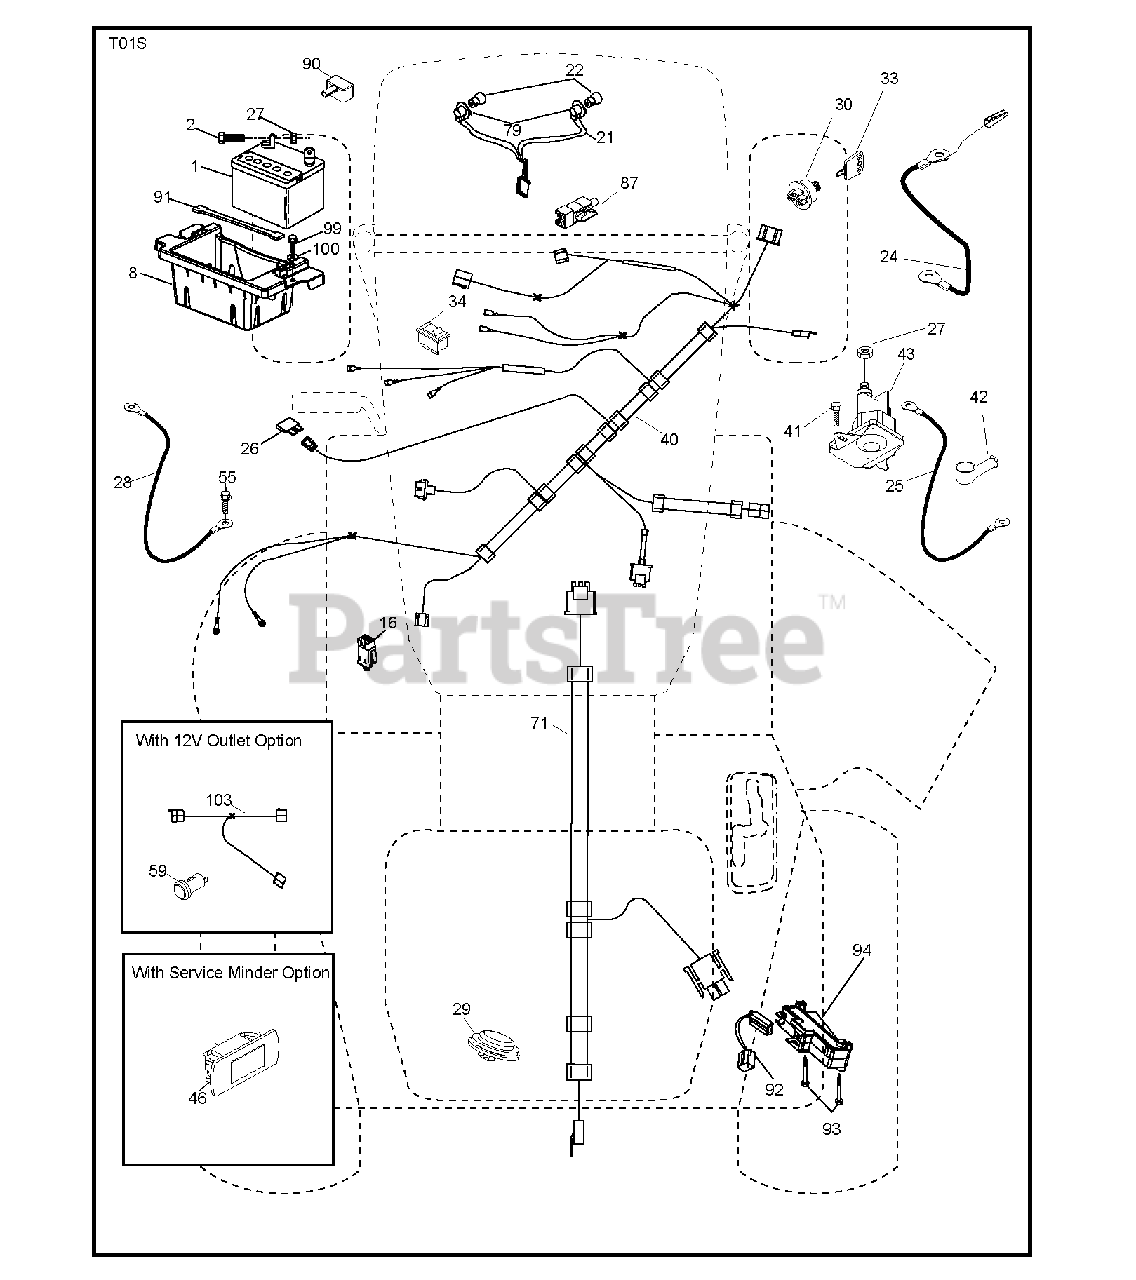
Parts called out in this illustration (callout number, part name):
1	REPL BY 532 12 38-99
8	BOX.BATTERY.MOUNT.FRONT.LT
16	SWITCH INTERLOOK PUSH-IN
21	HARNESS ASSY LIGHT
22	LIGHTBULB
24	CABLE.BATT.POS.WIRE.TG.DA SOL
25	CABLE.STARTER.6GA.BL/RED.14.
26	FUSE 20AMP
27	NUT
28	CABLE GROUND 6 GA 21" 90T BLK
29	SWITCH.SEAT.DELTA.OPC.
30	SWITCH.IGN.DELTA.W.LGH.ROS
33	KEY.CHAIN.BLISTER.PACK.GEN.INT
34	SWITCH LT
40	HARNESS IGN. DASH
41	SCREW
42	TERMINAL COVER
43	SOLENOID.W/BRASS.PLUNG
46	GUAGE.SRVCMNDR.HRMTR.
55	SCREW 5/16"
71	HARNESS-CHASSIS SUB
79	BULB HOLDER ASM.
87	SWITCH.INTRLCK.CLUTCH.
90	COVER.TERMINAL.BATTERY
91	STRAP, BATTERY MOUNT
92	HARNESS.PIGTAIL.CONSLE
93	SCREW.PLASTITE
94	MODULE.REVERSE.ROS
99	SCREW HEXWSHR 1/4-20X3/4
